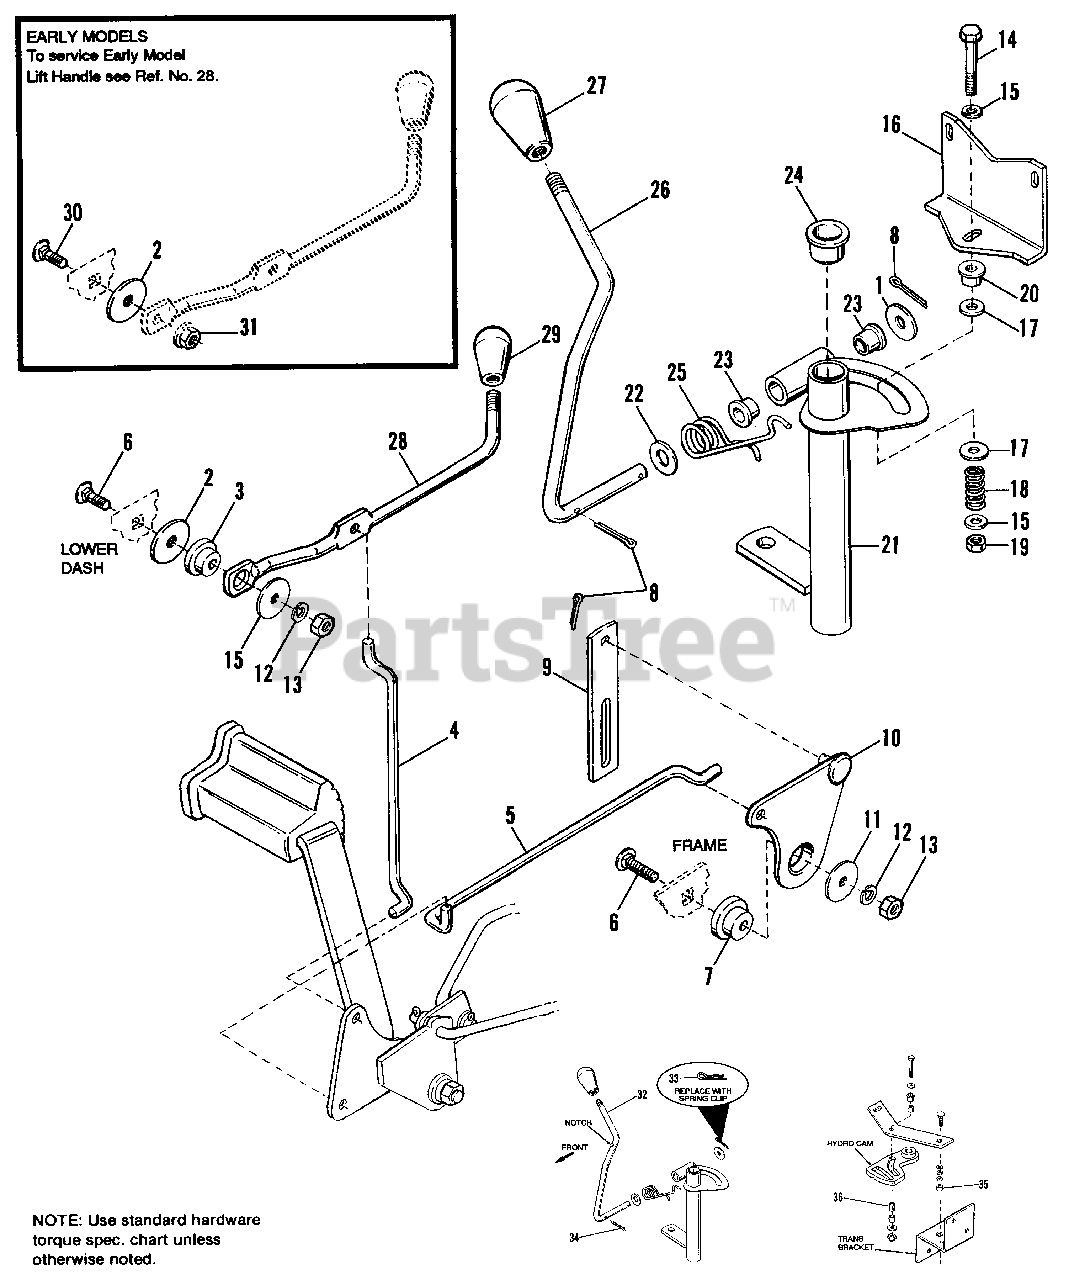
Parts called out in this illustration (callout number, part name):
1	WASHER, 1/2
2	WASHER, Plain, 13/32 x 1-1/2 x 1/8
3	SPACER, Special
4	LINK, Lift Upper
6	CARRIAGE BOLT, 5/16-18 x 1-1/4
7	SPACER, Special
8	COTTER PIN
9	LINK, Lift, Upper Transport
10	CAM, Lift Assy.
11	WASHER, Plain, 21/64 x 1-1/4
12	LOCKWASHER, 5/16
13	NUT, Hex, 5/16-18
14	CAPSCREW, 5/16-18 x 1-3/4
15	WASHER, Plain, 5/16
16	BRACKET, Tension
17	WASHER, Plain, 5/8, 21/32
19	NUT, Hex, Esna Lock, 5/16-18
21	SHIFT LEVER ASSY.
22	WASHER, Plain
23	BUSHING, Plastic, 1/2 Dia.
24	BUSHING, Nylon, 3/4 Dia.
25	SPRING, Torsion
26	LEVER, Shift
27	KNOB, Plastic
28	ROD, Lift Handle (Early Models)
28	ROD, Lift Handle (Later Models)
29	KNOB
30	CARRIAGE BOLT, 5/16-18 x 1 (Early Models Only)
31	NUT, Hex Range Lock, 5/16-18 (Early Models Only)
